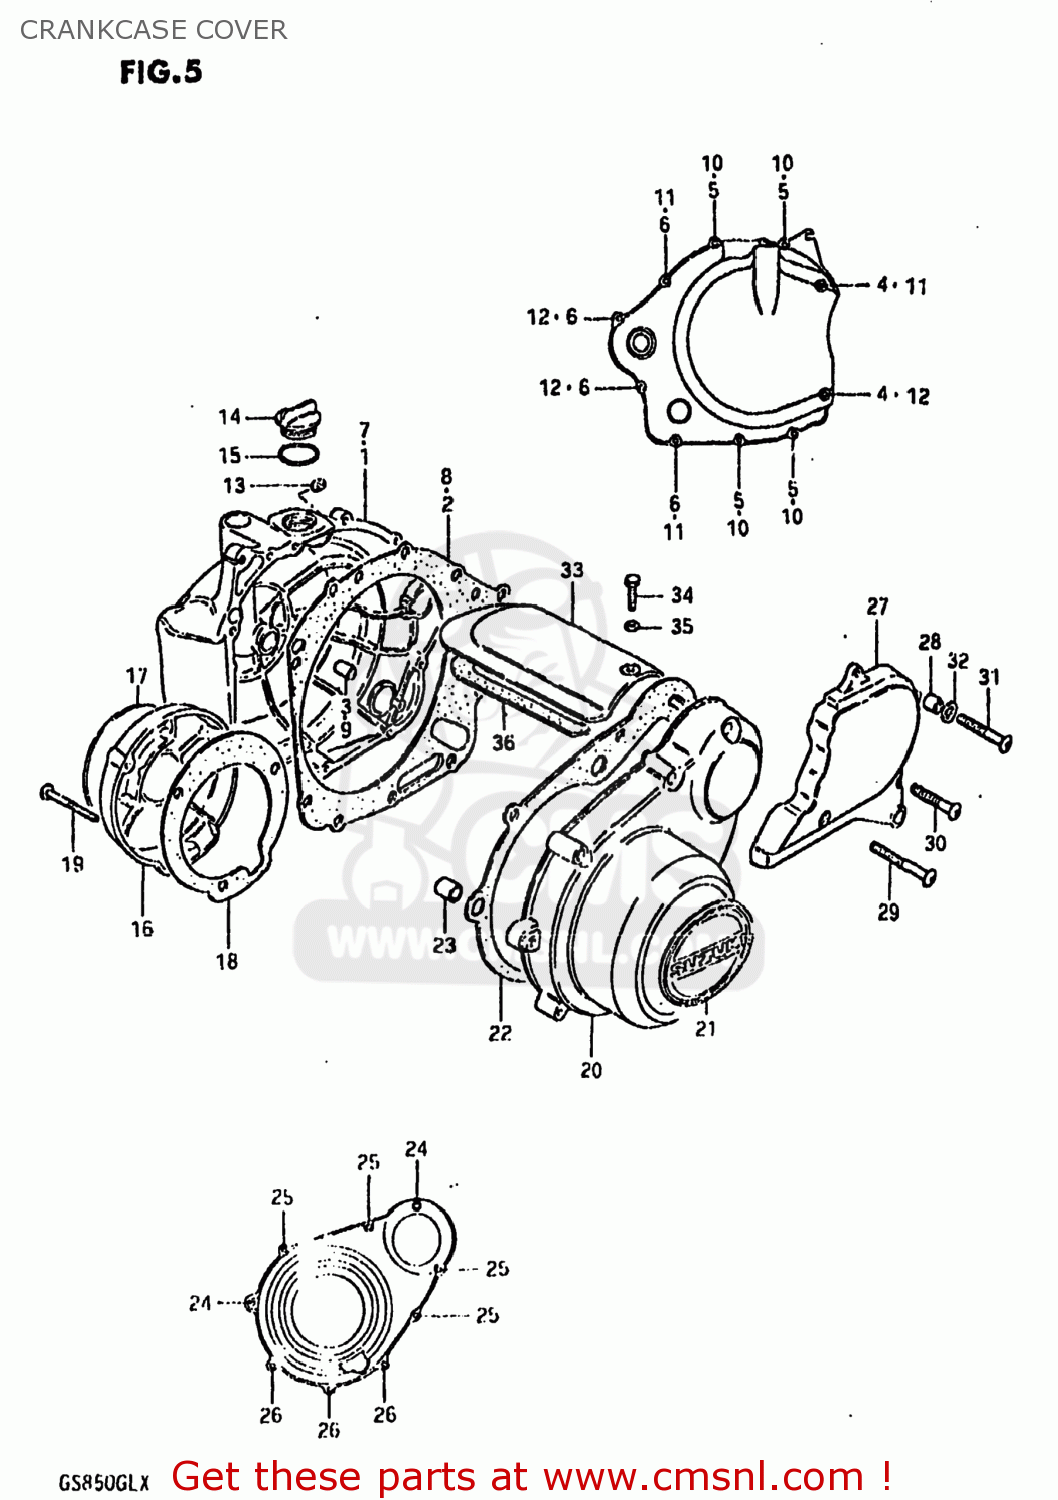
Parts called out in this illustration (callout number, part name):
1	COVER,CLUTCH
2	GASKET,CLUTCH COVER (MCA)
3	PIN
4	SCREW 6X65
5	SCREW
6	SCREW
7	COVER,CLUTCH
8	GASKET,MAGNETO COVER (N (MCA)
9	PIN
10	SCREW
11	SCREW 6X30
12	SCREW (6X35)
13	JET
14	CAP
15	O RING(D:2.2,ID:32)
16	COVER,CONTACT BREAKER
17	EMBLEM,CONTACT BREAKER COVER
18	GASKET,CONTACT BREAKER COVER (NAS)
19	SCREW
20	COVER
21	EMBLEM,MAGNETO COVER
22	GASKET,MAGNETO COVER (MCA)
23	PIN
24	SCREW (6X45)
25	SCREW
26	SCREW (6X35)
27	COVER,SPROCKET
28	PIN
29	SCREW 6X30
30	SCREW
31	SCREW
32	WASHER
33	COVER,STARTER MOTOR
34	BOLT
35	WASHER
36	GASKET,STARTER MOTOR COVER (MCA)
